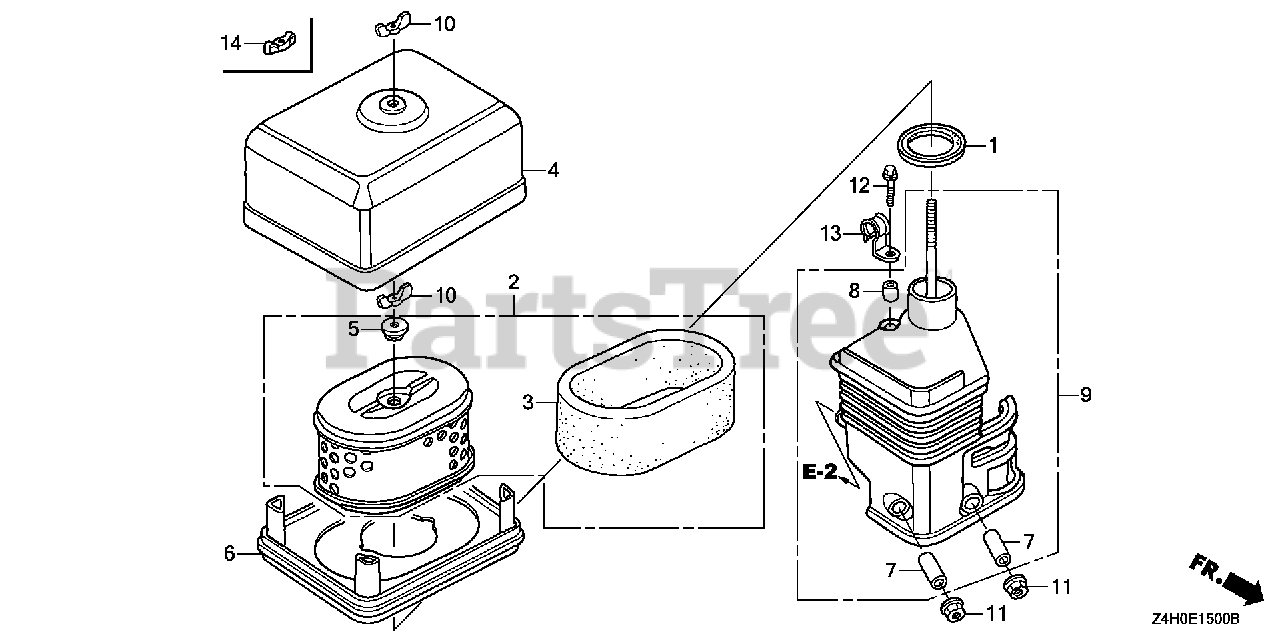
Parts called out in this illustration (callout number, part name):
1	GASKET, ELBOW
2	ELEMENT, AIR CLEANER (DUAL)
3	FILTER (OUTER)
4	COVER, AIR CLEANER
5	GROMMET, AIR CLEANER
6	NOSE, MUFFLER
7	COLLAR, AIR CLEANER
8	COLLAR B, AIR CLEANER
9	ELBOW, AIR CLEANER
10	NUT, TOOL BOX SETTING
11	NUT, FLANGE (6MM)
12	BOLT, FLANGE (6X20)
14	NUT, AIR CLEANER
